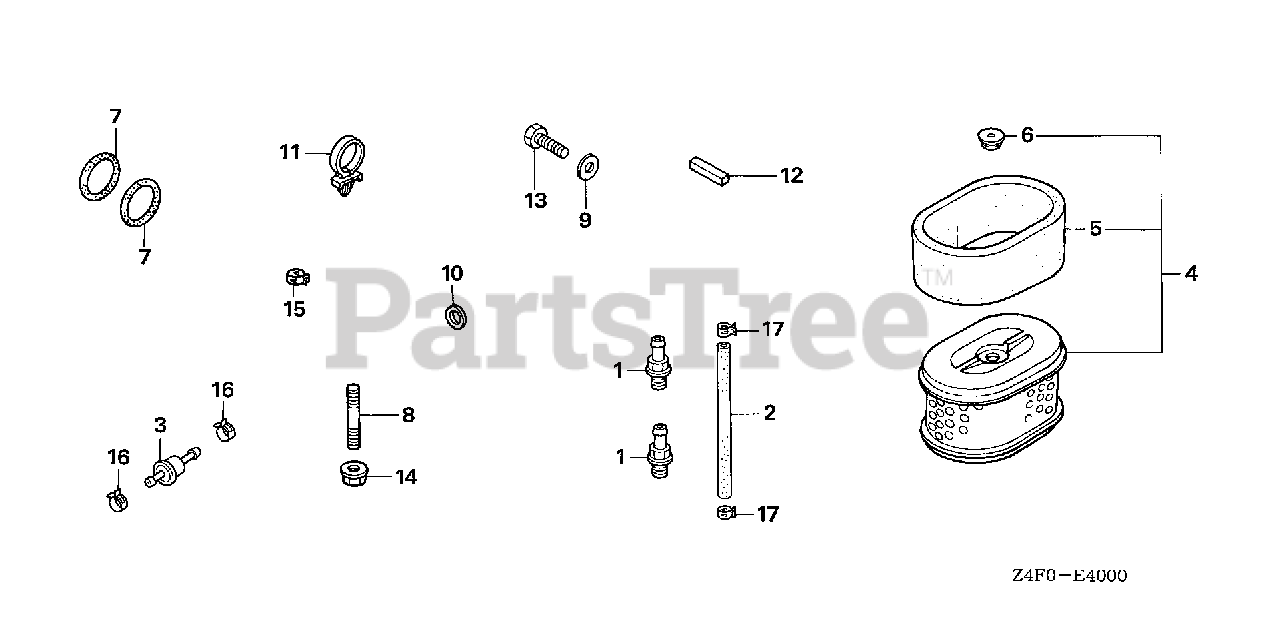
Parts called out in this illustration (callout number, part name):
8	BOLT, STUD (10X32)
8	BOLT, STUD (10X60)
14	NUT, FLANGE (10MM)
